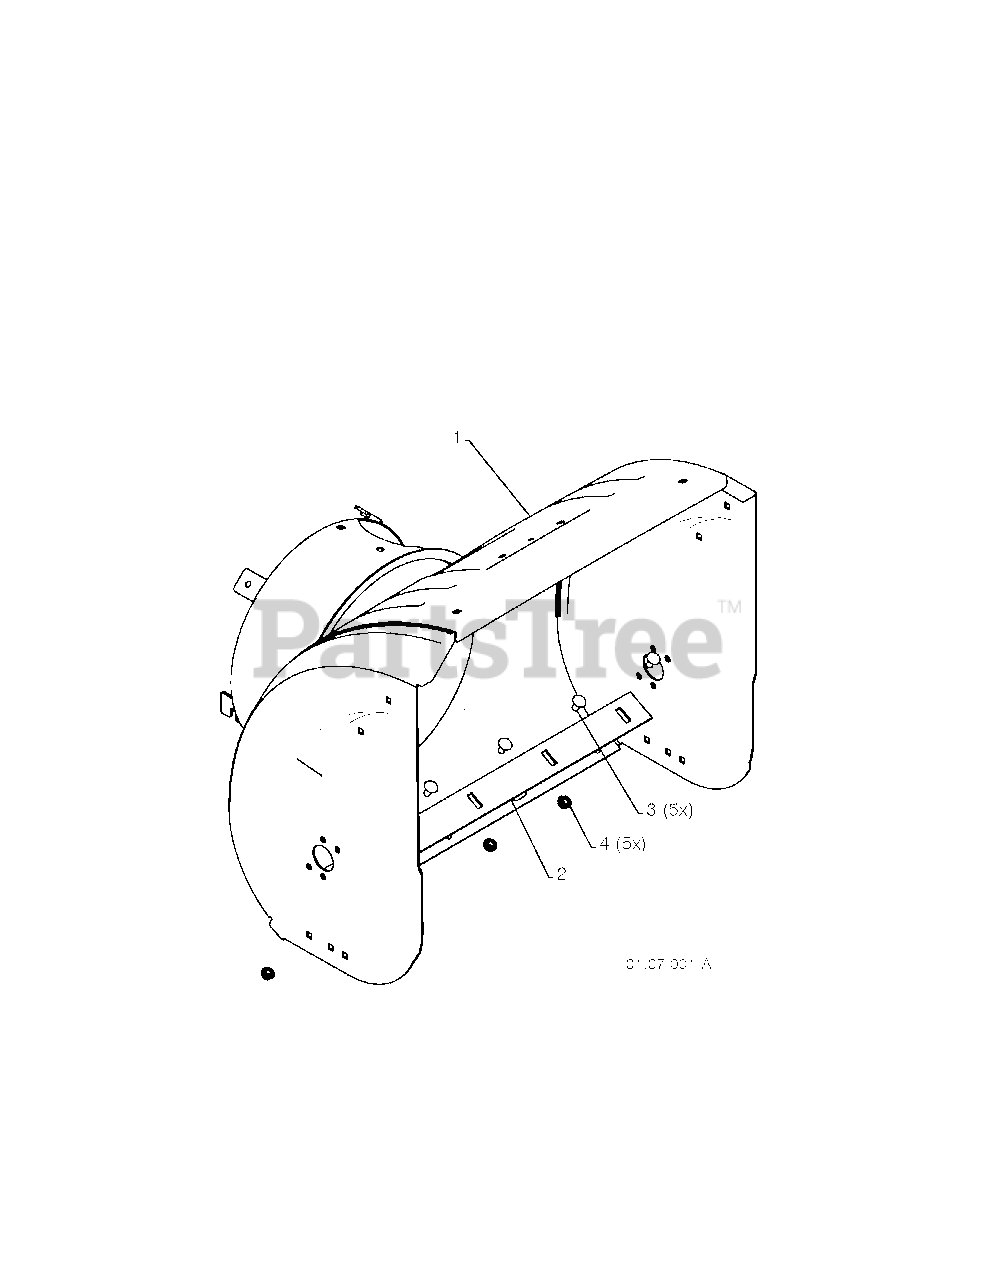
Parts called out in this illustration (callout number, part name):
2	BAR, SCRAPER
3	BOLT
4	NUT.FLANGE.5/16
